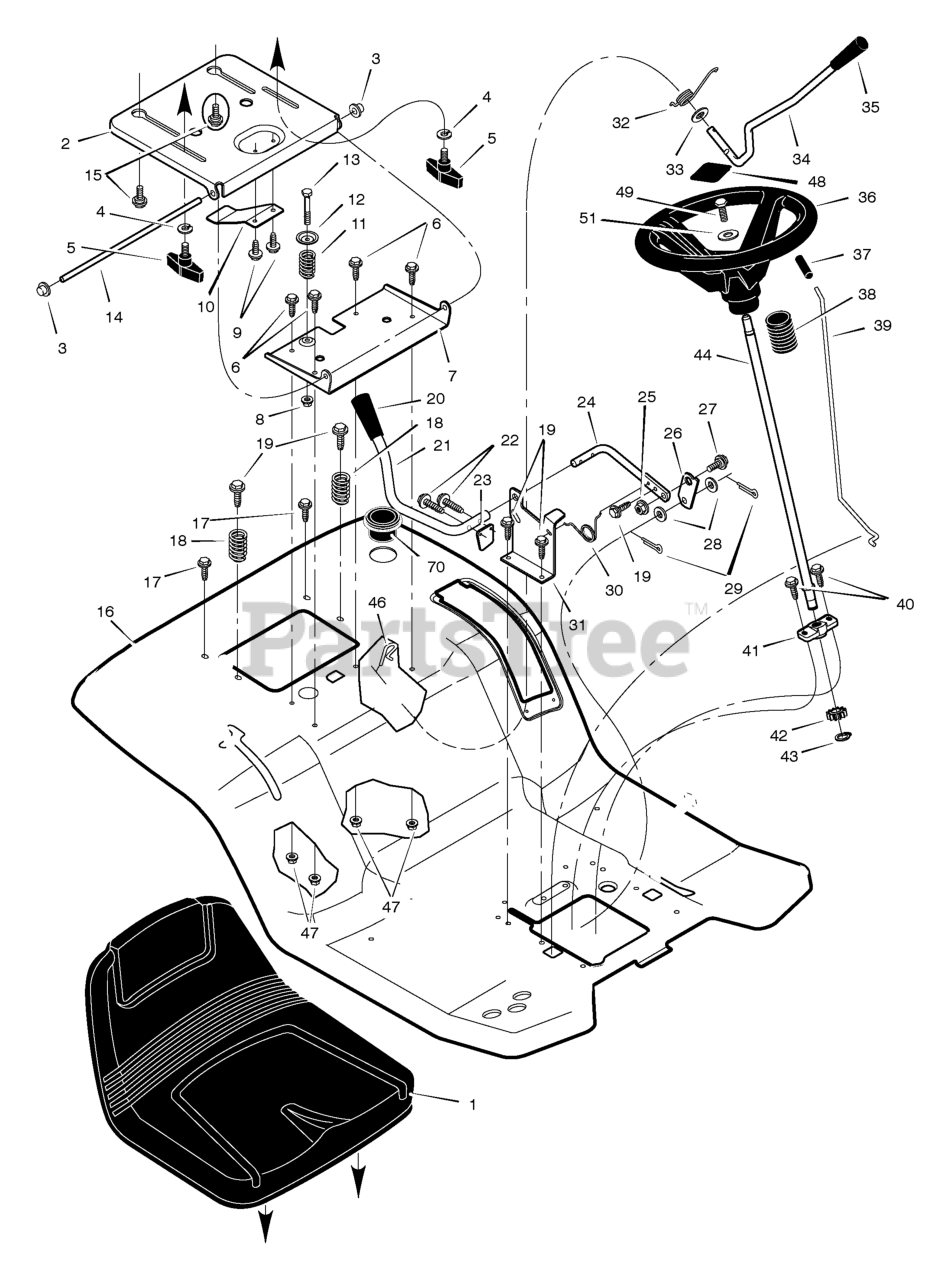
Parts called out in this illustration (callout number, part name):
1	Seat
2	Support, Seat
3	Push-On Cap
4	Washer
5	Bolt, Wing
6	Bolt
7	Bracket, Pivot
8	Nut
10	Spring, Leaf
11	Spring
12	Washer, Cup
14	Rod, Pivot
15	Bolt, Shoulder
16	Deck, Seat
20	Grip
21	Handle, PTO
22	Screw, Hex
23	Paddle, Switch
24	Lever, PTO
25	Nut
26	Link, PTO
27	Shoulder, Bolt
29	Pin, Cotter
31	Bracket, PTO
34	Handle, Lift
35	Grip
36	Wheel, Steering
38	Bellows
39	Rod, Parking Brake
41	Bearing, Lower
42	Gear, Pinion
44	Shaft, Steering
46	Pin, Cotter
47	Nut
48	Insert, Steering Wheel
49	Screw, Hex
51	Washer
70	Holder, Cup
